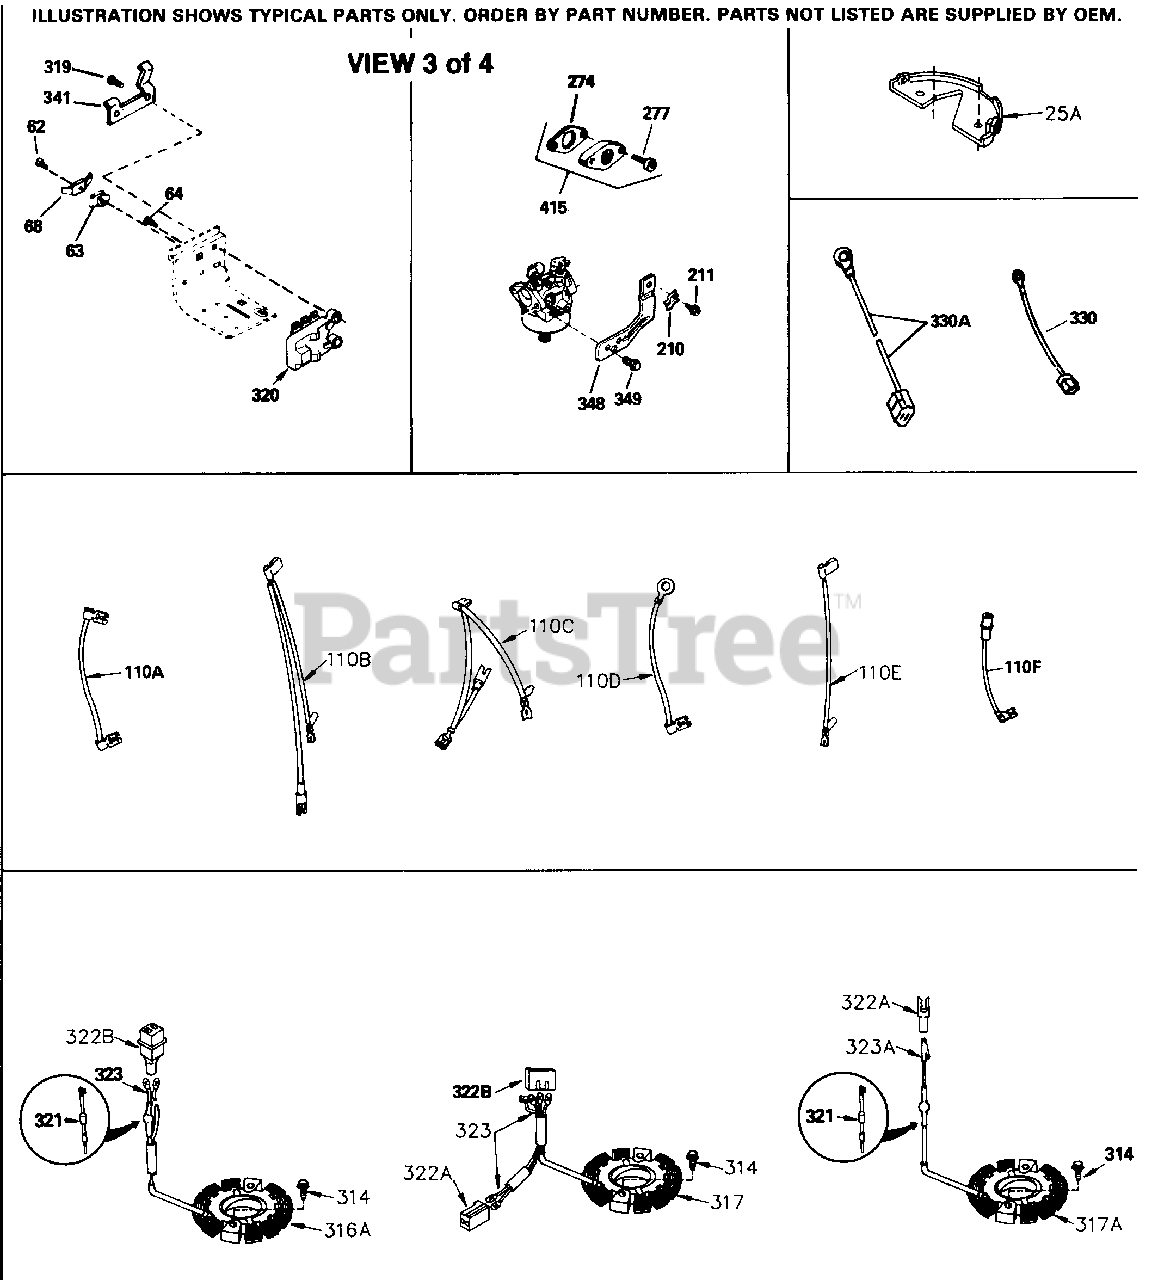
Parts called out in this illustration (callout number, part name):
28	Lock Nut, 8-32
62	Screw, 8-32 x 3/8"
63	Breather Tube Grommet
64	Screw, T-30, 1/4-20 x 1/2"
68	Ground Terminal
203	Compression Spring
204	Screw, 6-32 x 1-1/8"
210	Conduit Clip
211	Screw, 10-32 x 3/8"
238	Screw, 10-32 x 1-17/32"
245A	Pre-Cleaner Air Filter also available in Packaged Part #740015B
277	Screw, 5/16-18 x 3-3/16"
314	Screw, 1/4-20 x 3/4"
315	Alternator Coil Incl. 321, 322 & 323
323	Terminal
330	Wire Harness
